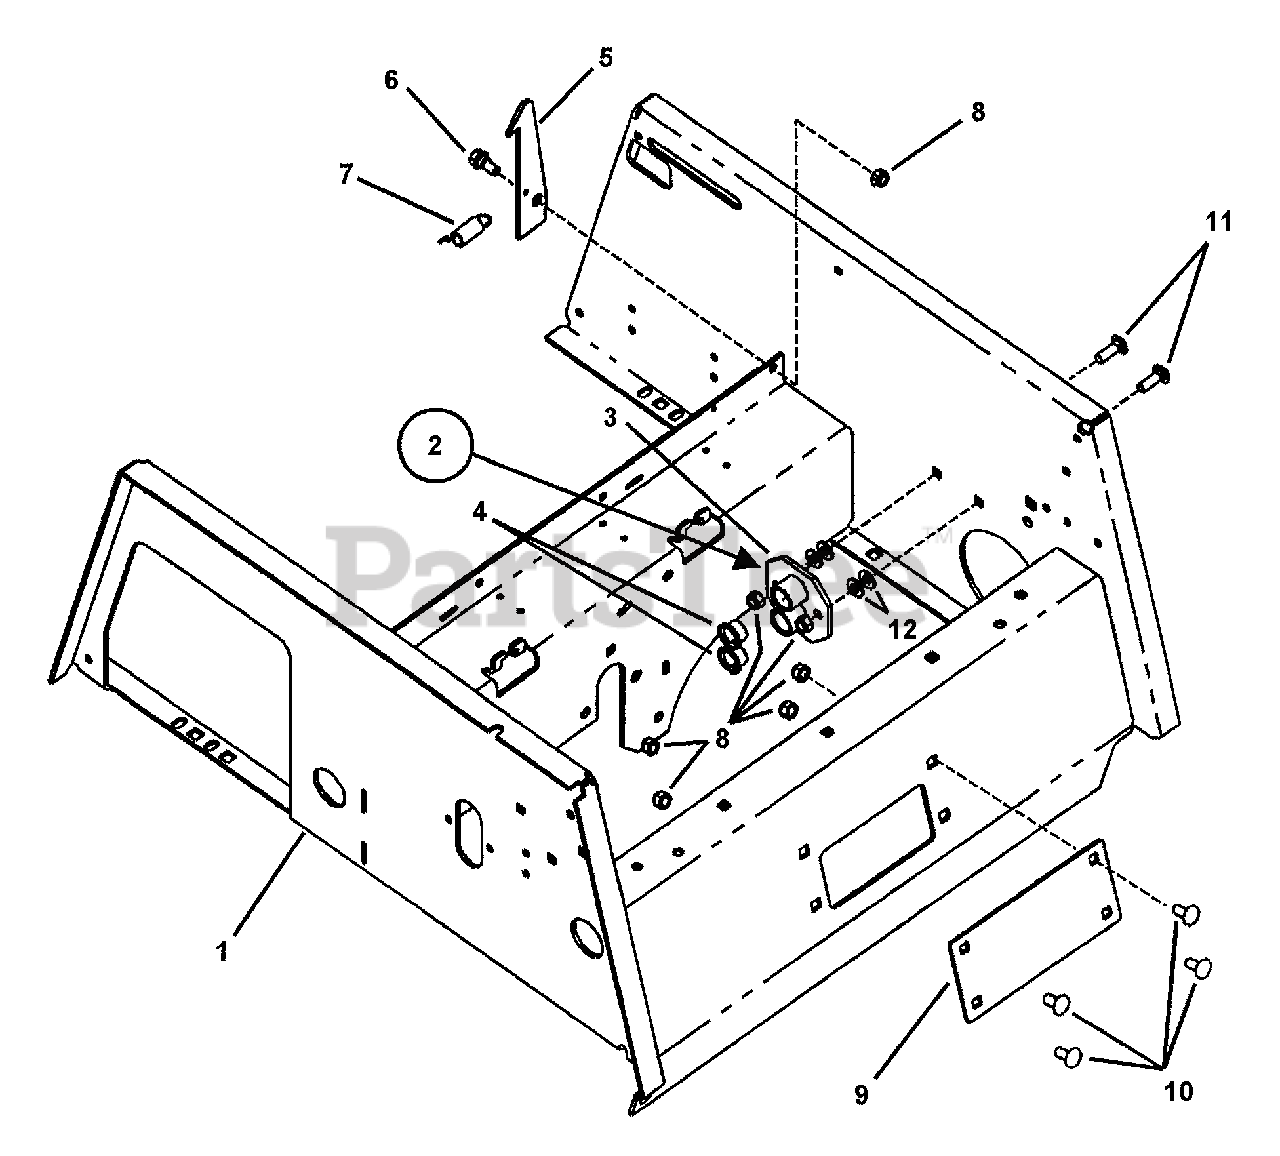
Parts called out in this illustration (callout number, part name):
1	WELDMENT, Upper Chassis
2	ASSEMBLY, Bushing Support
3	WELDMENT,Bushing Support
4	BUSHING, 5/8" (Teflon Impregnated)
5	LATCH, Seat Support
6	BOLT, 5/16-18 Shoulder
7	SPRING
8	NUT, 5/16-18 HEX NYLON LOCK
9	PLATE, Cover
10	BOLT, 5/16-18 x 3/4" Carriage
11	BOLT, 5/16-18 X 1" Square Neck Carriage, Grade 5
12	WASHER, 5/16" Flat
